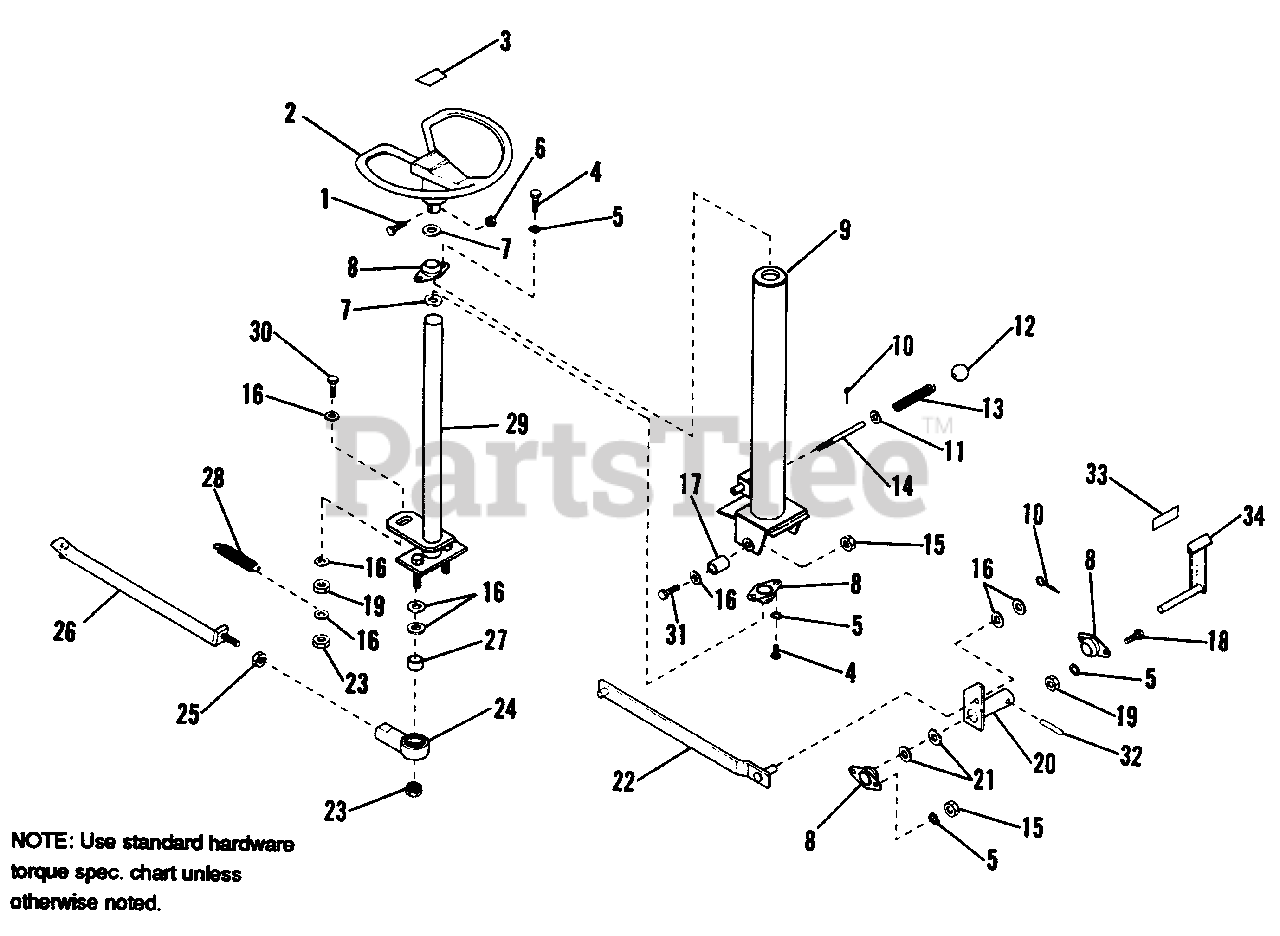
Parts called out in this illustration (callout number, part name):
1	CAPSCREW, Hex 3/8-16 x 1-1/2
2	WHEEL, Steering
3	INSERT, Steering Wheel
4	CAPSCREW, Hex 5/16-18 x 1/2
5	LOCKWASHER, Spring 5/16
6	LOCKNUT, Hex 3/8-16
7	WASHER, Plain
8	BEARING, Flanged
9	STEERING COLUMN ASSY.
11	WASHER, Plain
14	ROD, Latch
15	LOCKNUT, Hex, Flanged 5/16-18
16	WASHER, Plain
18	CAPSCREW, Hex 5/16-18 x 3/4
19	NUT, Hex 5/16-18
20	CLUTCH ARM ASSY.
21	WASHER, Plain
22	LINK ASSY., Clutch, Front
23	LOCKNUT, Hex 5/16-18
25	NUT, Hex 5/16-24
26	LINK ASSY., Steering
29	SHAFT ASSY.
30	CAPSCREW, Hex 5/16-18 x 1-1/4
31	CAPSCREW, Hex 5/16-18 x 1
33	PAD, Non-Skid
34	CLUTCH PEDAL ASSY.
